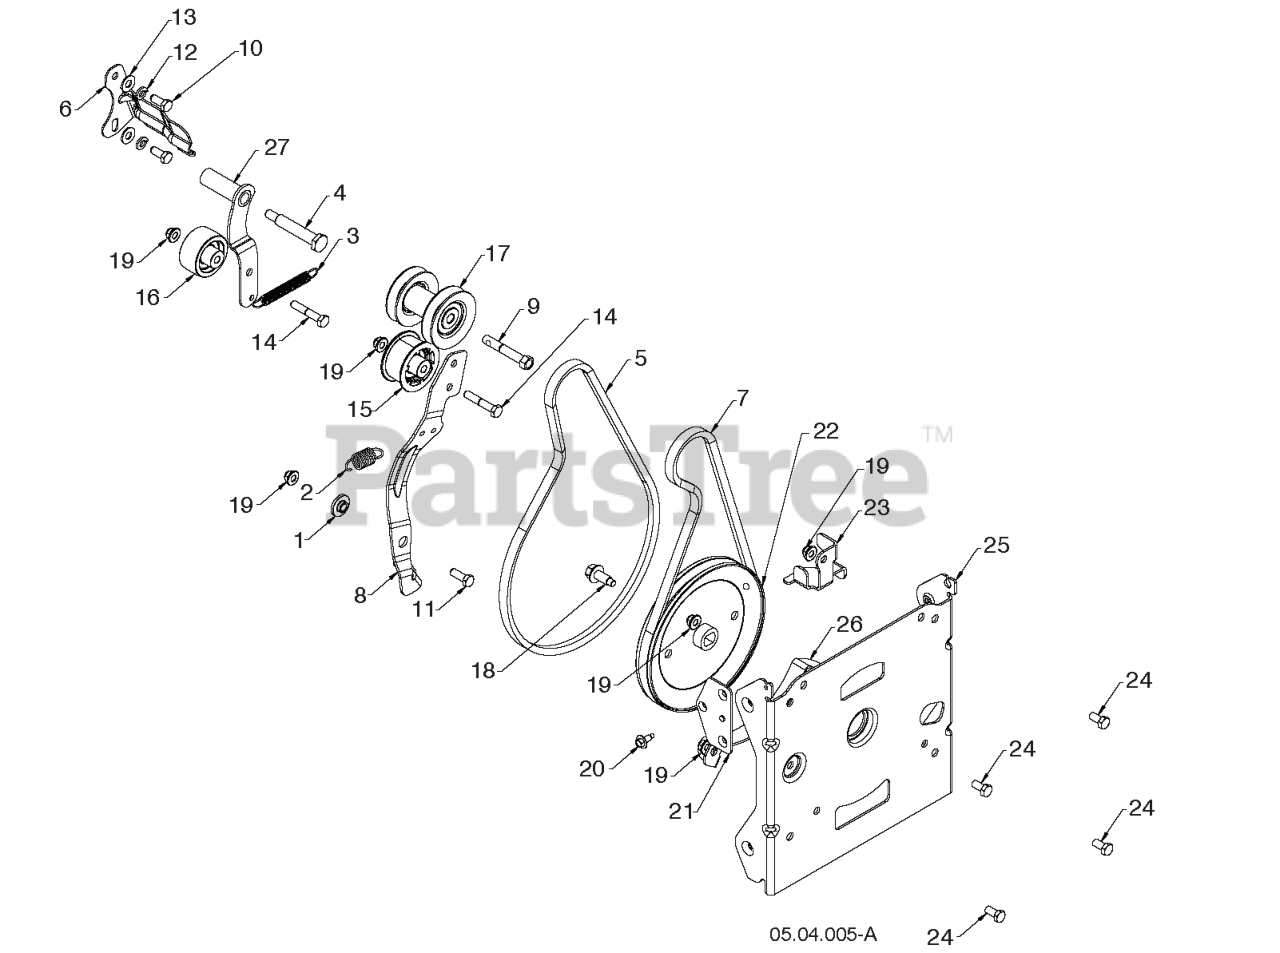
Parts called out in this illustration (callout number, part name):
1	BUSHING.BRAKE.ARM
2	SPRING RETURN, IDLER ARM, IMPE
3	SPRING RETURN IDLER ARM
4	BOLT 5/16-24X2.25 HEX HEAD SHO
5	BELT.DRIVE.SNOW.DUAL
6	BELT KEEPER BRACKET
7	LOW CRANK IMPELLER BELT
8	ARM.IDLER.AUTO-PH.676
9	BOLT.ENGINE.PULLEY
10	SCREW 5/16-24 X .75 GR5
11	Hex, Bolt 5/16 x 18 UNC x 7/8 (AYP part number)
12	Washer Lock Hvy Hlcl 1/4 (Order from Engine Manufacturer) (AYP part number)
13	Washer 11/32 x 3/4 x 16 Gauge (AYP part number)
14	Bolt, Hex 5/16-18 x 1-3/4 (AYP part number)
15	PULLEY,IDLER,2.00 W SPA
16	PULLEY.IDLER.FLANG.2.O/SPACER
17	PULLEY.ASM.IMPELLER/DRIVE
18	SCREW FLANGE HEAD CAP WITH DOG
19	NUTNYLOK.FLRANGE.5/16-18
20	HEX.WASHER.HEAD 1/4-20 X .65
21	BRACKET NUT BLACK ZINC PLATE
22	PULLEY IMPELLER DD 4L
23	GUIDE.LOWER.AUGER.BELT.479
24	BOLT, HEX HEAD 5/16-18
25	BRACKET.AUG.HOUSING.INTER.BLAC
26	BRACKET.BELT.KEEPER.LOWER.BLAC
27	ARM IDLER DRIVE WELDMENT_HOT
